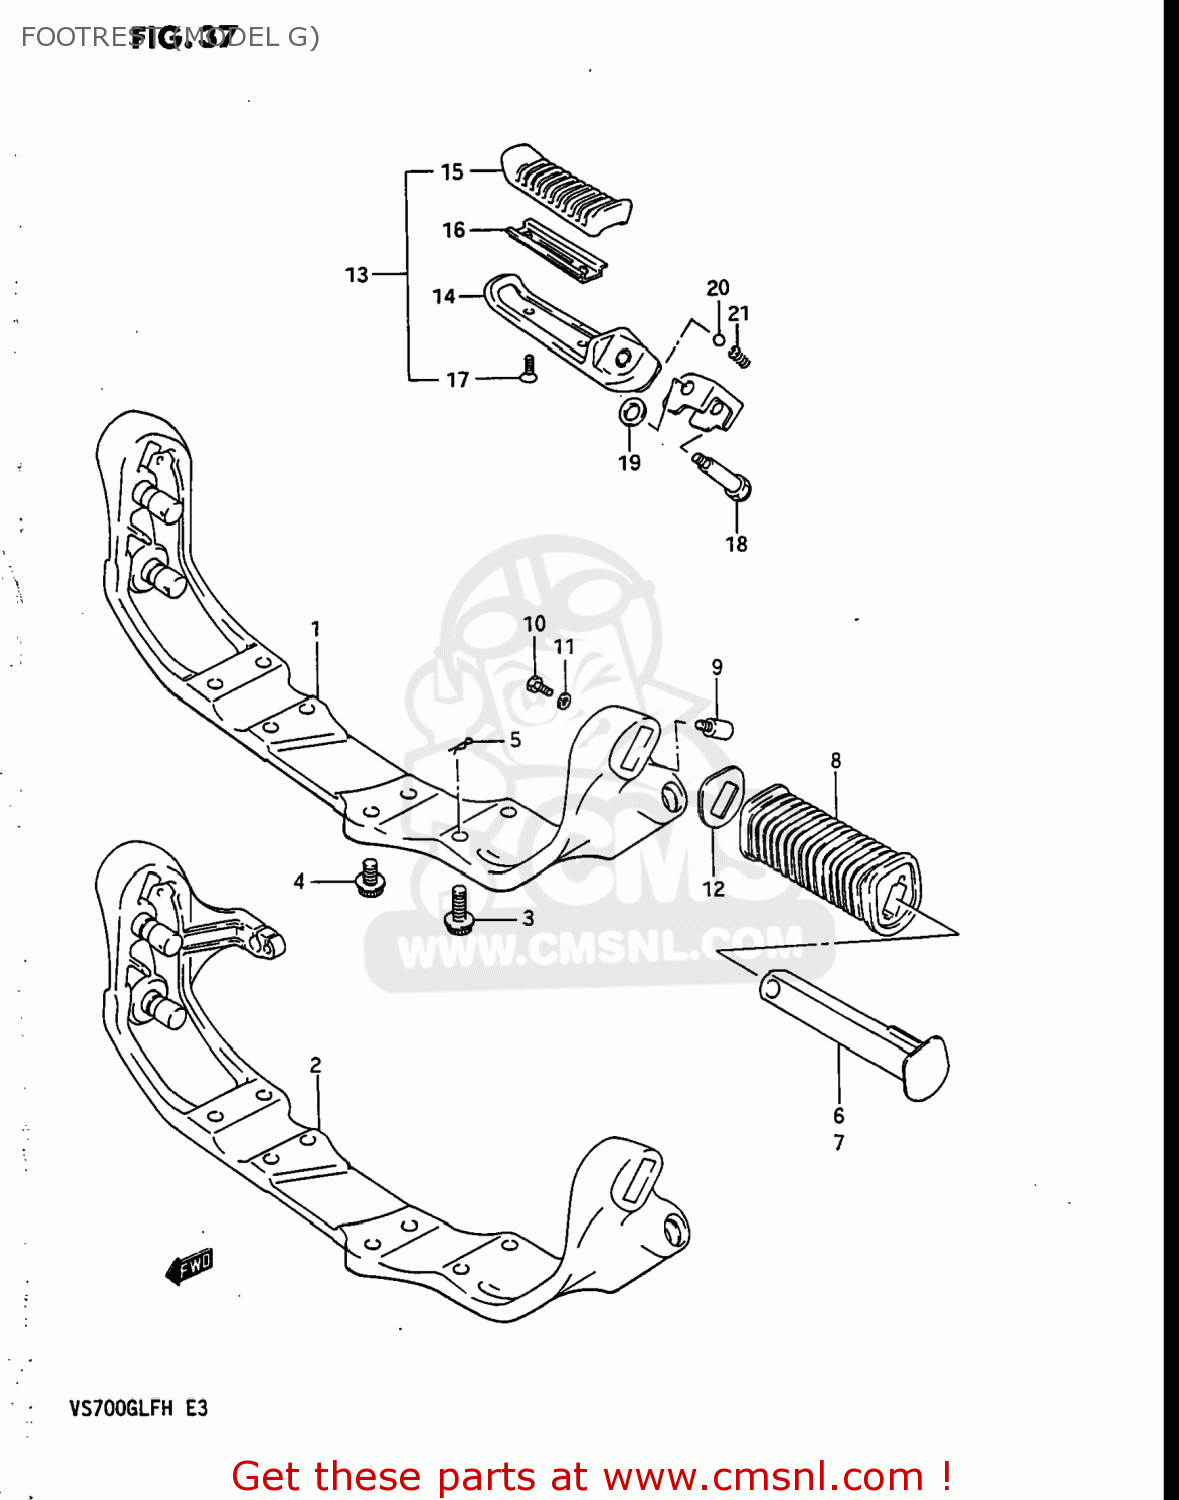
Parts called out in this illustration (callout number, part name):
1	BRACKET,FRONT FOOTREST
2	BRACKET COMP,FRONT FOOTREST
3	BOLT(8X25)
4	BOLT
5	PIN,SNAP
6	BAR,FR FOOTREST,R
7	BAR,FR FOOTREST,L
8	RUBBER,FR FOOTREST
9	BOLT,FRONT FOOTREST RUBBER
10	BOLT 5X12
11	LOCK WASHER
12	WASHER,FR FOOTREST
13	FOOTREST ASSEMBLY,REAR
14	BAR COMP,PILLION FOOTREST
15	RUBBER,PILLION FOOTREST
16	PLATE,RUBBER STOPPER
17	SCREW 5X16
18	BOLT(6X34.5)
19	SHIM
20	BALL
21	SPRING
